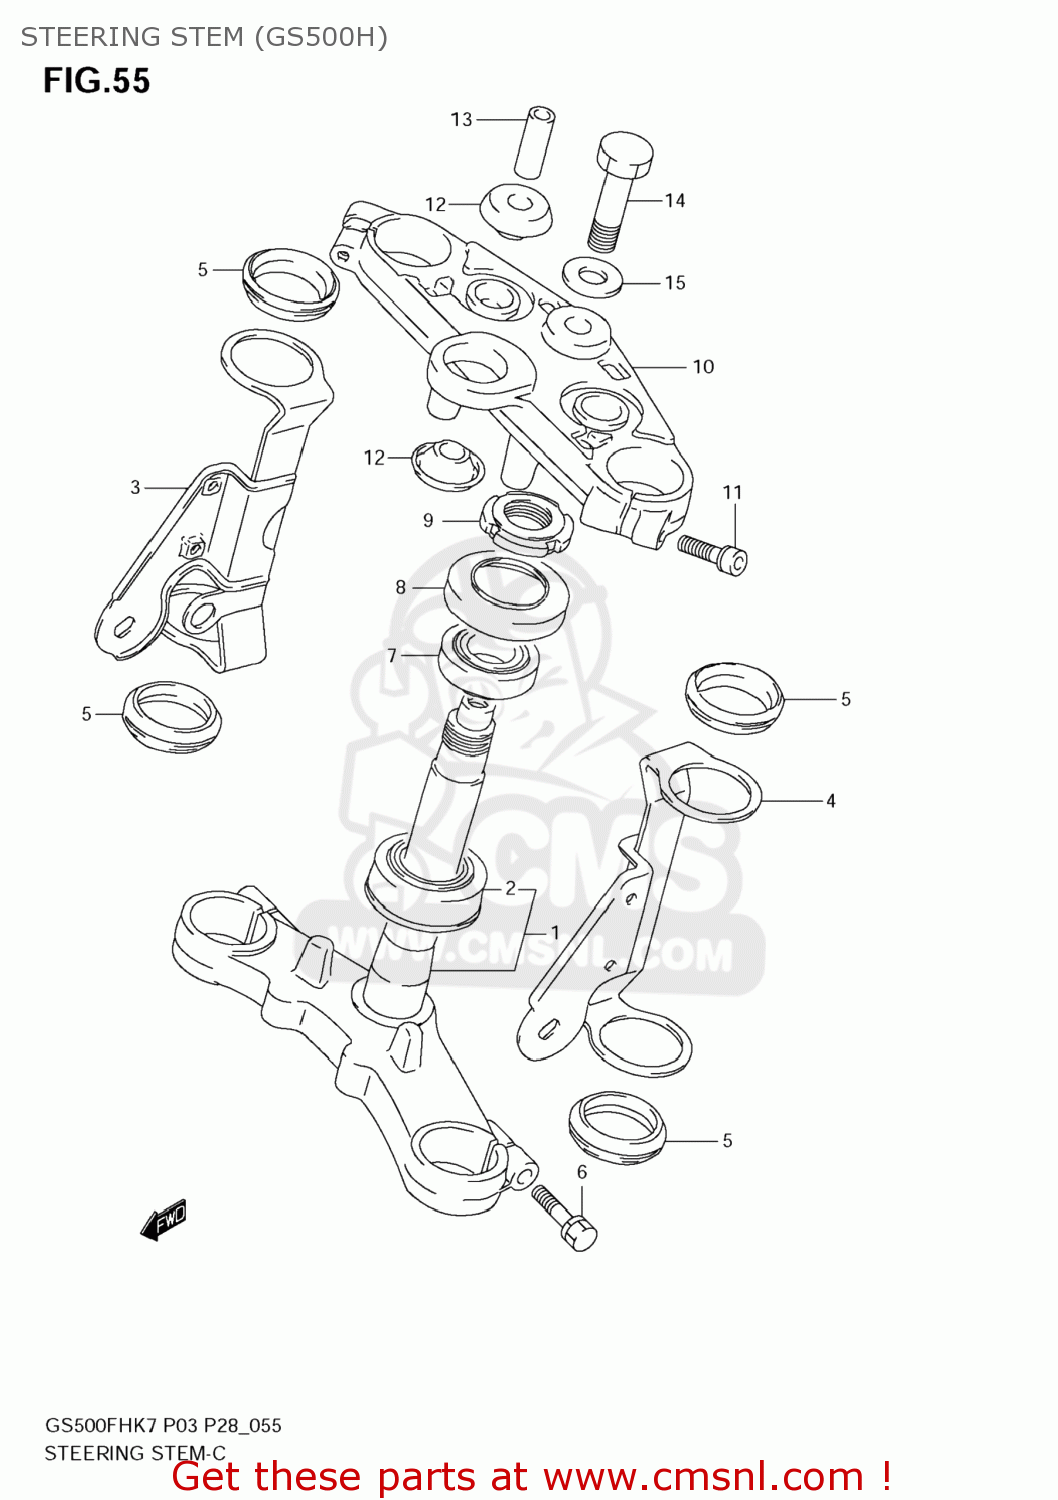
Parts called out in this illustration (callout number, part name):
1	STEM, STEERING
2	BEARING(30X55X17)
3	BRACKET, HEADL
4	BRACKET,HEADLA
5	CUSHION,HEADLAMP BRACKET
6	BOLT,STEERING
7	BEARING(25X47X15)
8	SEAL,STEERING UPR DUST
9	NUT,STEERING STEM(25X44X10)
10	HEAD STEERING
11	BOLT
12	CUSHION, STEM HEAD
13	SPACER, HEAD S
14	BOLT, UPPER
15	WASHER
